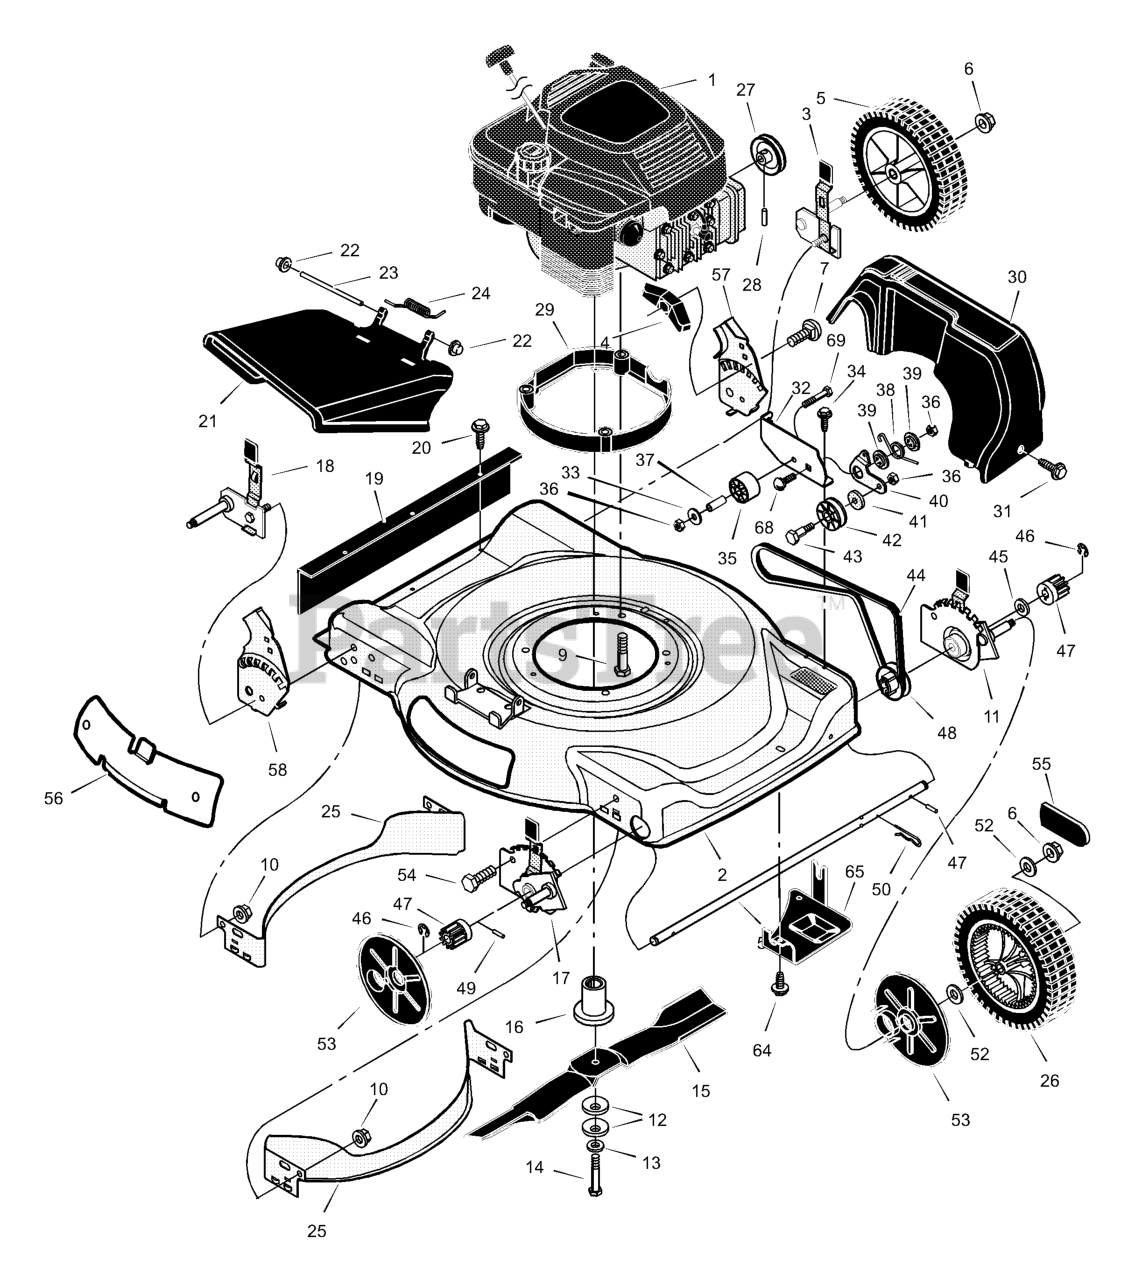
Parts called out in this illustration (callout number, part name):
1	Engine
2	Housing
3	Height Adjuster, Left Rear
5	Wheel and Tire, Rear
6	Locknut, Flange
7	Bolt, Carriage
9	Bolt, Engine
10	Nut
11	Height Adjuster, Left Front
12	Washer, Belleville
14	Bolt, Hex
16	Adapter, Blade
17	Height, Adjuster, Right Frt.
18	Height, Adjuster, Right Rr.
19	Guard, Rear
21	Deflector, Chute
22	Push-On Cap
23	Pin, Pivot
26	Wheel and Tire, Drive
28	Pin, Spring
29	Base, Engine
30	Cover, Belt (Black)
32	Bracket, Idler Support
35	Idler, Backside
36	Locknut
37	Bearing
40	Arm, Pivot
42	Pulley, Idler
43	Bolt, Shoulder
44	Belt, Briggs
46	Ring, Retainer
47	Gear, Pinion
49	Pin, Drive
50	Pin, Hair
52	Washer
53	Cover, Dust
54	Bolt
55	Hub Cap
56	Plate, Mulch
57	Bracket, Left Handle
58	Bracket, Right Handle
65	Shield, Debris
68	Bolt, Carriage
